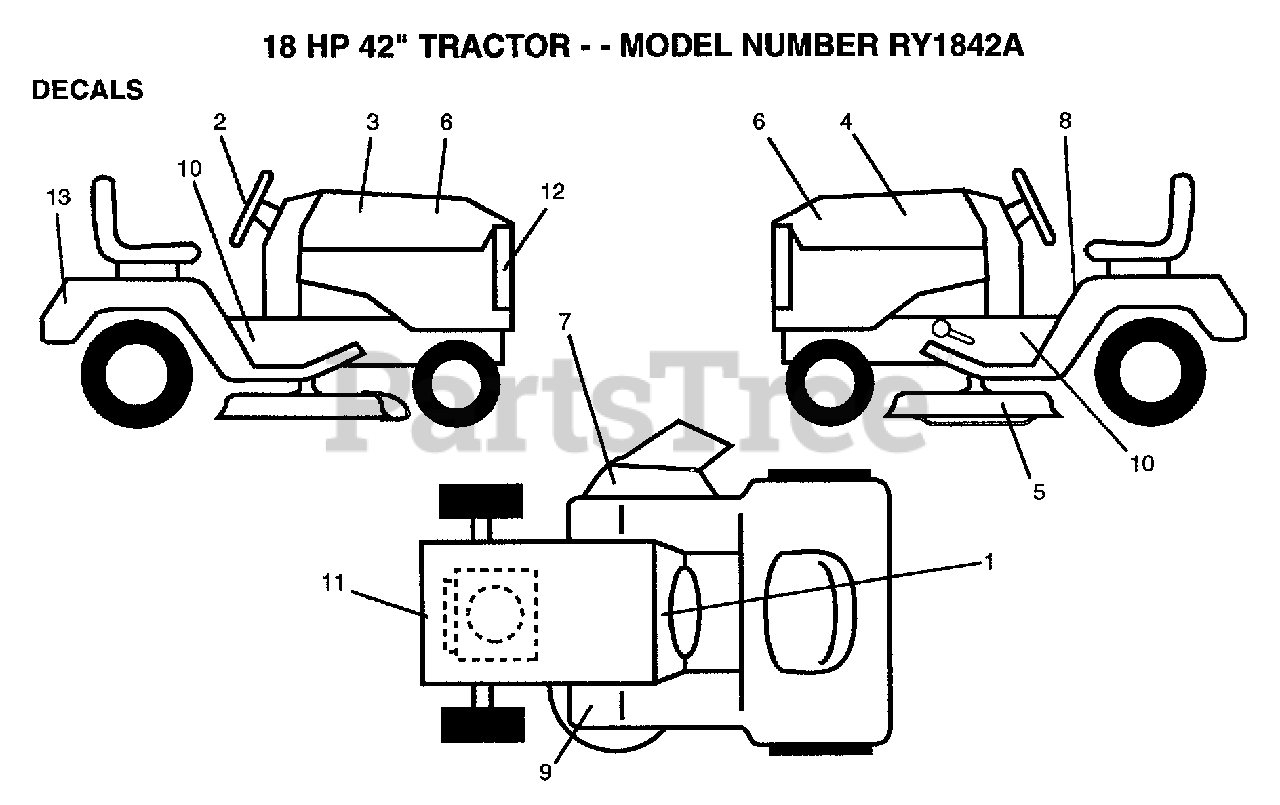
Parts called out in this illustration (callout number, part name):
2	"DECAL,STR WHL"
4	DECAL HOOD LH
5	DECAL YT
6	DECAL PANEL T
7	DECAL WARNING
8	DECAL CAUTION
9	DECAL T
10	CHASSIS DECAL
11	DECAL.ENG.272757
12	DECAL GRILL
13	FENDER DECAL
